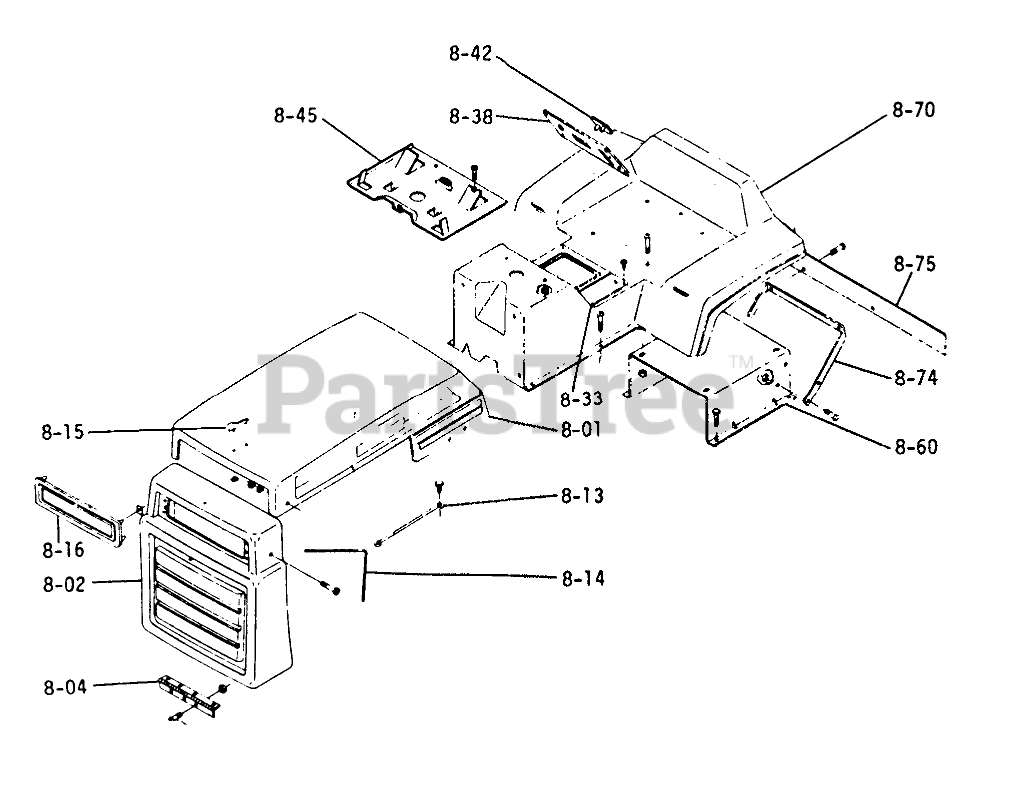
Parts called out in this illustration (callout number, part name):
8-02	Grill
8-04	Hinge-Hood
8-13	LINK
8-14	Cord-Hood Stop
8-15	Hood Ornament
8-16	ESCUTCHEON PLATE
8-33	Plate-Shift Pattern
8-38	Panel-Complete-Lettered-EL
8-42	Plug Button
8-45	Support-Tank
8-60	Support Seat
8-70	Body
8-74	Support-Fender
8-75	Bar-Fender Support
8-91-A	Mat, RH footrest
